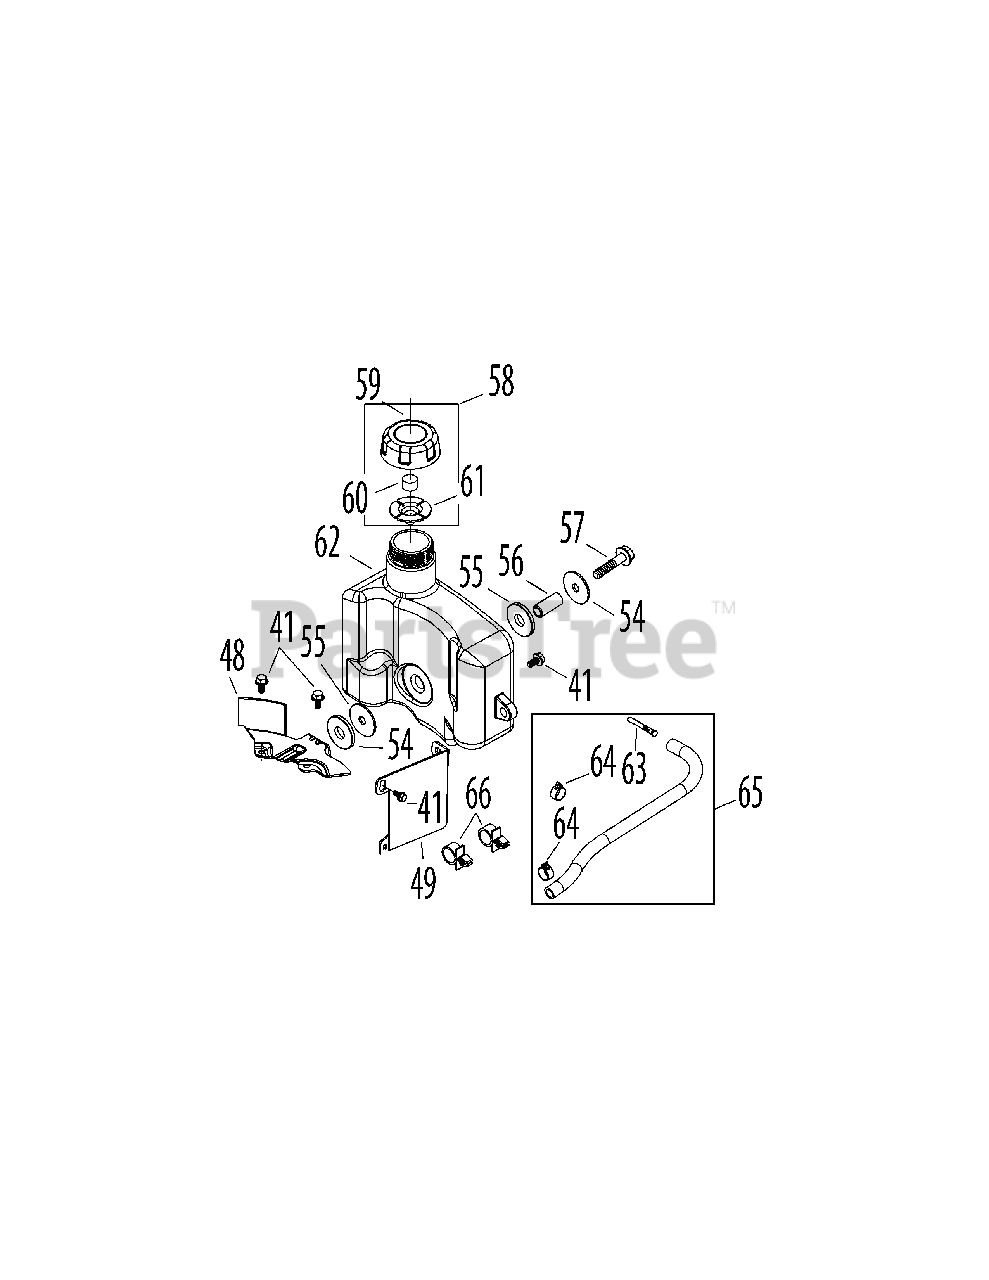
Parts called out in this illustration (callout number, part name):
41	Bolt M6×14
48	Fuel Tank Bottom Bracket
49	Tank/Label Bracket
54	Fuel Tank Washer
55	Rubber Bushing
56	Fuel Tank Bushing
57	Tank/Sump Bolt M8x50
58	Fuel Cap Assembly
59	Fuel Cap
60	Foam Insert
61	Vent Gasket
62	Fuel Tank Assembly
63	Fuel Filter
64	Fuel Hose Clamp
65	Fuel Line Kit
66	Plastic Support Clamp
